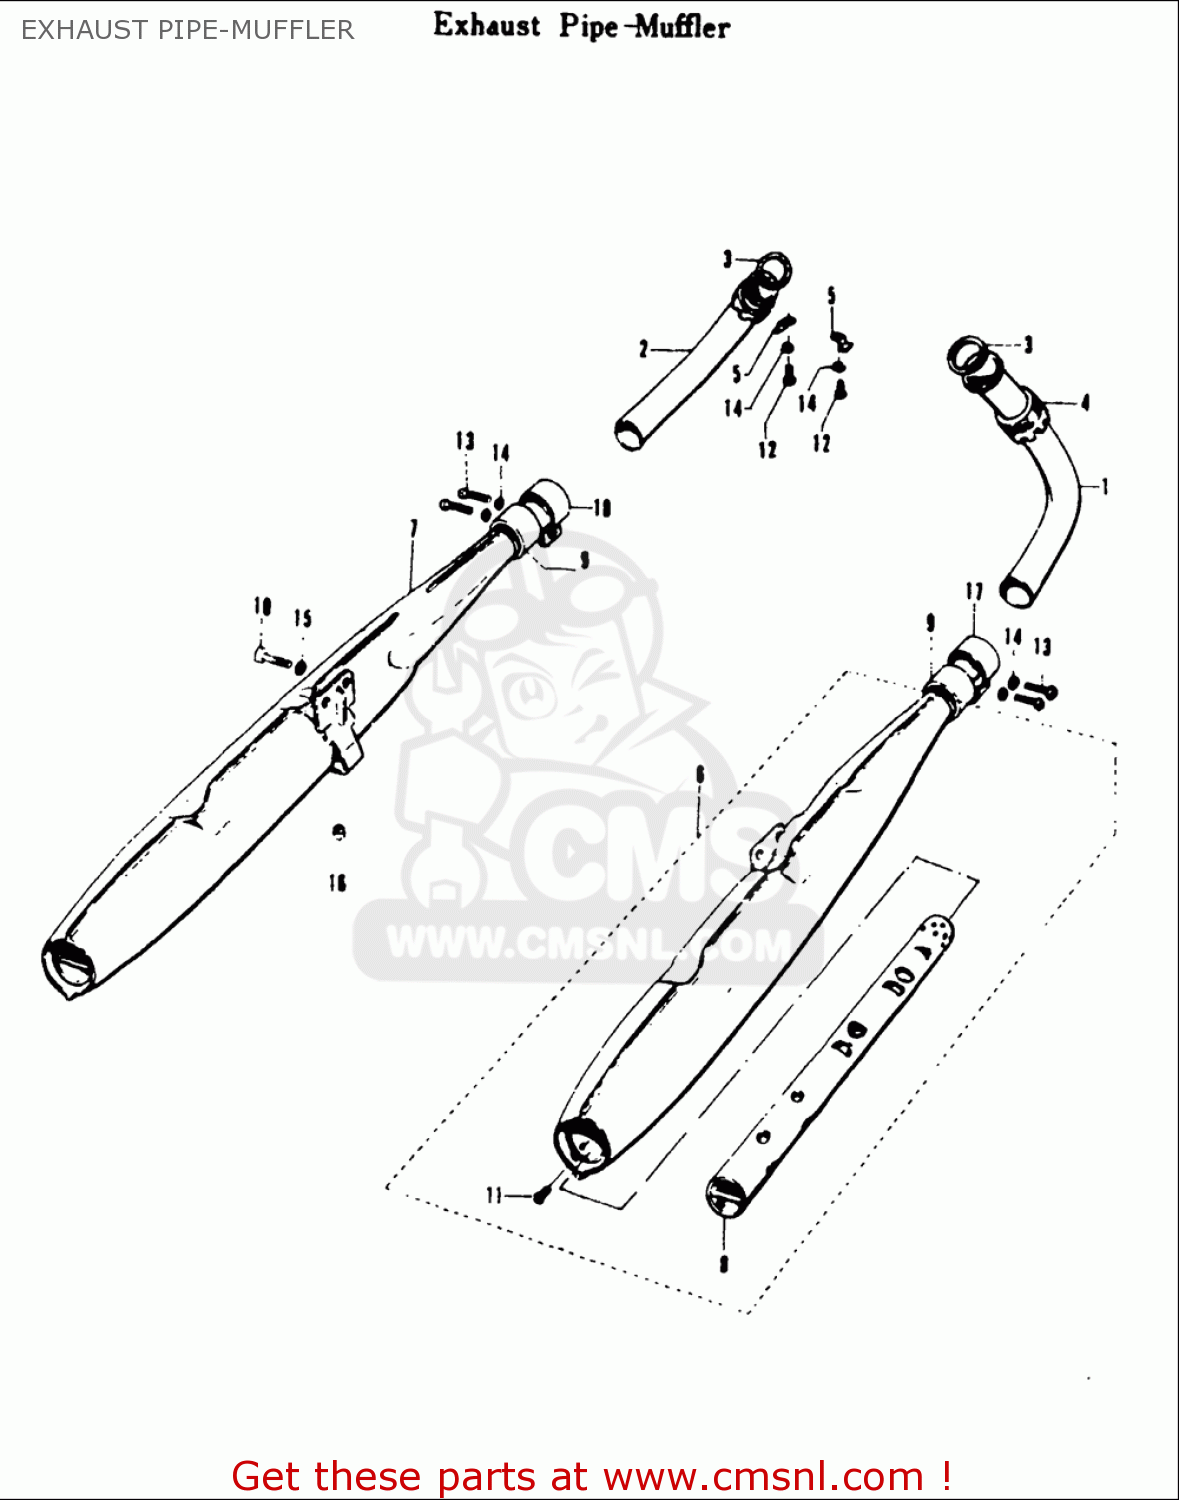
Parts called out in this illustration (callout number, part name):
3	GASKET,EXHAUST PIPE (NAS)
5	PLATE,EXHAUST PIPE
12	SCREW
14	WASHER,LOCK
15	WASHER,LOCK
16	CUSHION
